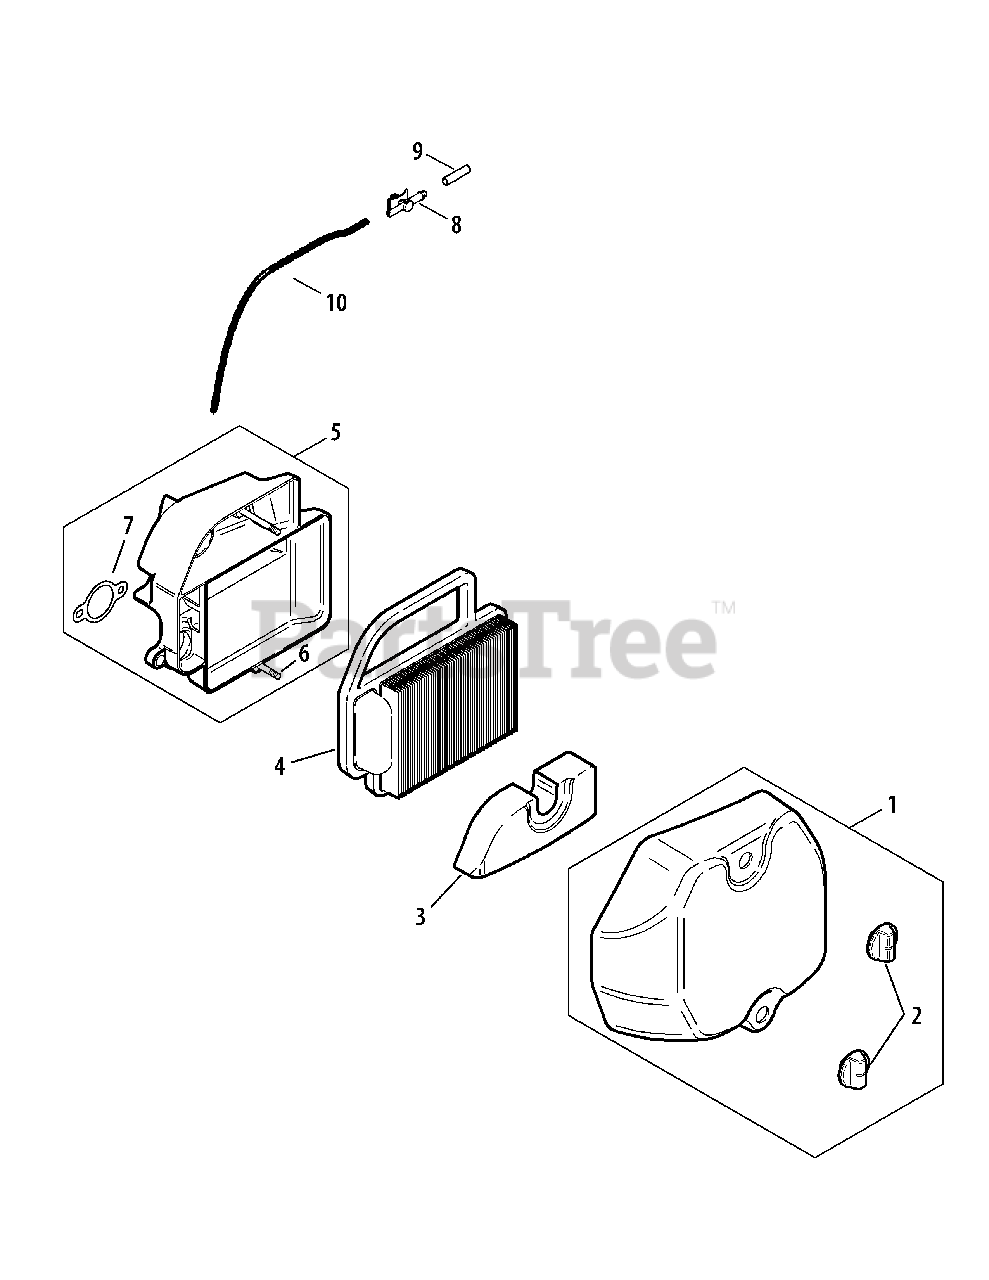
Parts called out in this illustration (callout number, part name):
1	Air Cleaner Cover Kit (Inc. 2)
3	Pre-Cleaner Element (Dry)
4	Air Cleaner Element
5	Air Cleaner Base Kit (Inc. 6, 7)
6	Air Cleaner Base Stud
7	Air Cleaner Base Gasket
8	Evaporative Connector
10	Hose, Evaporative 20"
